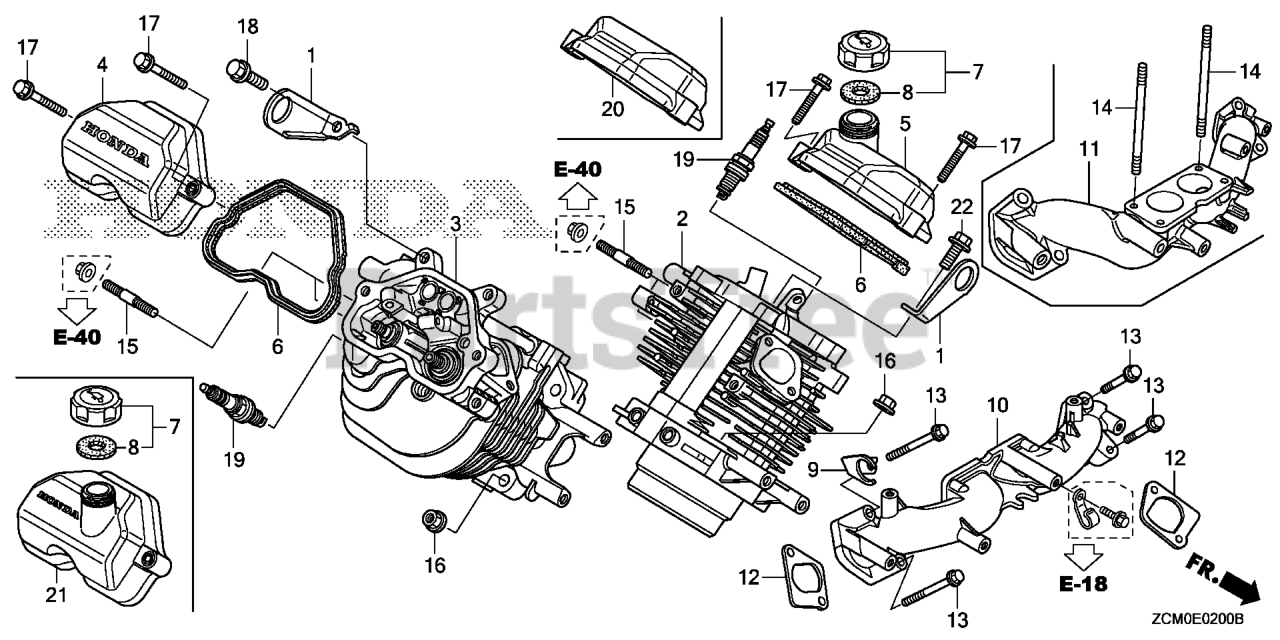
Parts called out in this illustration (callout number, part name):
1	HANGER, ENGINE
2	CYLINDER #1 COMP(
2	CYLINDER HEAD (#1)
3	CYLINDER HEAD (#2)
4	COVER, CYLINDER HEAD
5	COVER, CYLINDER HEAD
6	GASKET, HEAD COVER
7	CAP ASSY., OIL FILLER
8	GASKET, OIL FILLER CAP
11	MANIFOLD, IN.
12	GASKET, IN. MANIFOLD
13	BOLT, FLANGE (8X55)
14	BOLT, STUD (6X106)
15	BOLT, STUD (8X22)
16	NUT, FLANGE (10MM)
17	BOLT, FLANGE (6X30)
18	BOLT, FLANGE (8X16) Use from Engine SN 1000016.
19	SPARK PLUG (ZFR5F-4)
22	BOLT, FLANGE (8X16) Use from Engine SN 1000016.
